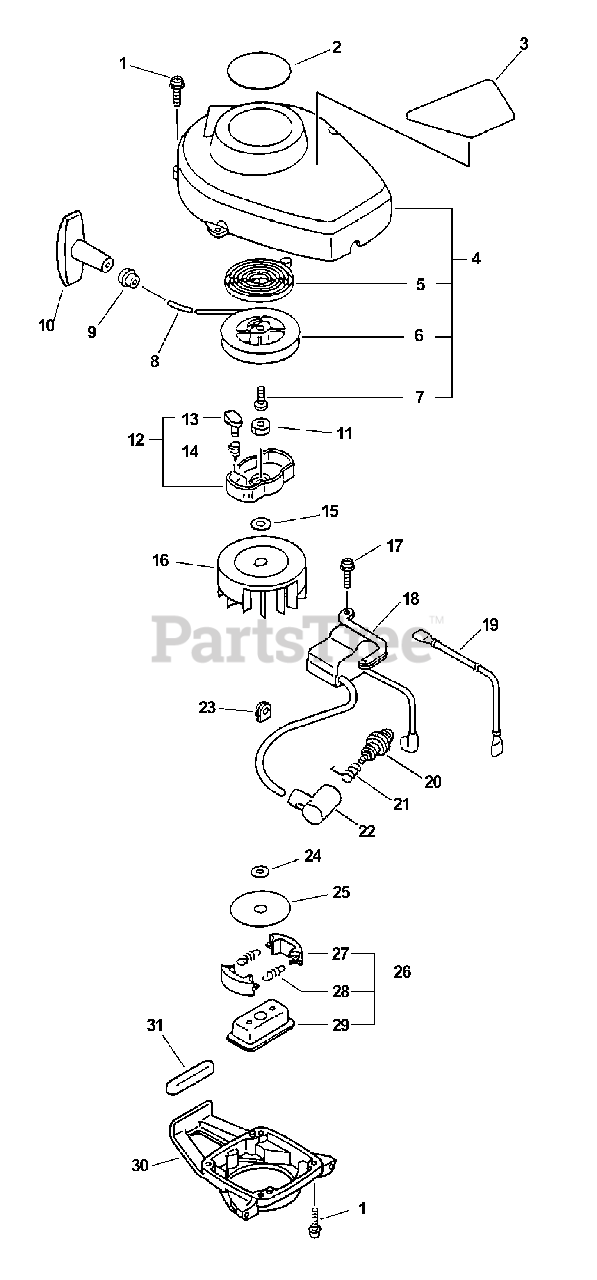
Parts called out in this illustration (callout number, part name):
1	BOLT 4×16
2	LABEL, HC-2400
2	LABEL, HC-2410
3	LABEL - CAUTION
4	STARTER ASSY
5	SPRING, RECOIL
6	REEL, ROPE
7	SCREW
8	ROPE, STARTER
9	GUIDE, ROPE
10	GRIP, STARTER
12	STARTER PAWL ASSY
13	PAWL, STARTER - BLACK
14	SPRING, RETURN
15	WASHER 8.5×16×1.2
17	SCREW 4×22
18	COIL, IGNITION
19	LEAD
20	SPARK PLUG - BPM-7Y
21	TERMINAL, SPARK PLUG
22	CAP, SPARK PLUG
24	WASHER, CLUTCH
25	PLATE, CLUTCH
26	CLUTCH ASSY
27	SHOE, CLUTCH
28	SPRING, CLUTCH
29	HUB, CLUTCH
30	CASE, CLUTCH
31	CUSHION, FUEL TANK
